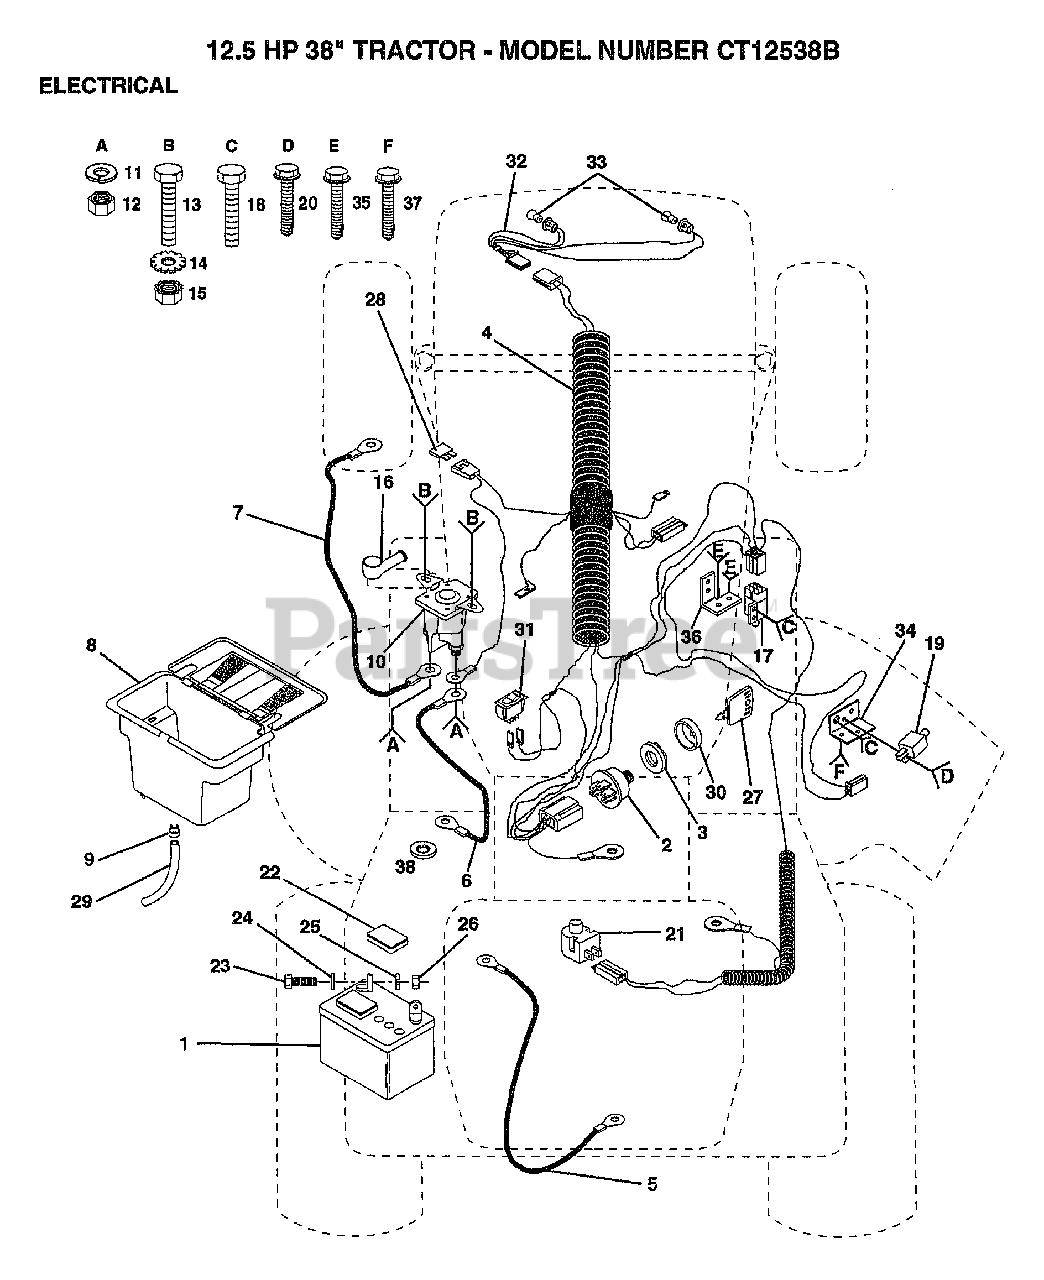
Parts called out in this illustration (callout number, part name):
3	NUT IGNITION
4	IGN HARNESS
5	CABLE T
7	"CABLE T, BATTERY"
9	HOSE CLAMP T
12	NUT
13	BOLT
15	NUT
17	SWITCH INTERLOCKT
18	SCREW
19	SWITCH-INTER. GT
20	SCREW
21	SWITCH SEAT
22	"CAP,BATTERY "
23	BOLT LT
24	WASHER
25	LOCKWASHER
28	FUSE HYT
29	"DRAIN TU T, BATT"
31	SWITCH LT
32	"HARNESS,LIGHT SOC"
33	HEADLAMP BULB
34	SWITCH BRACKET
35	SCREW
36	BRACKET LT
37	SCREW
38	LOCKWASHER
